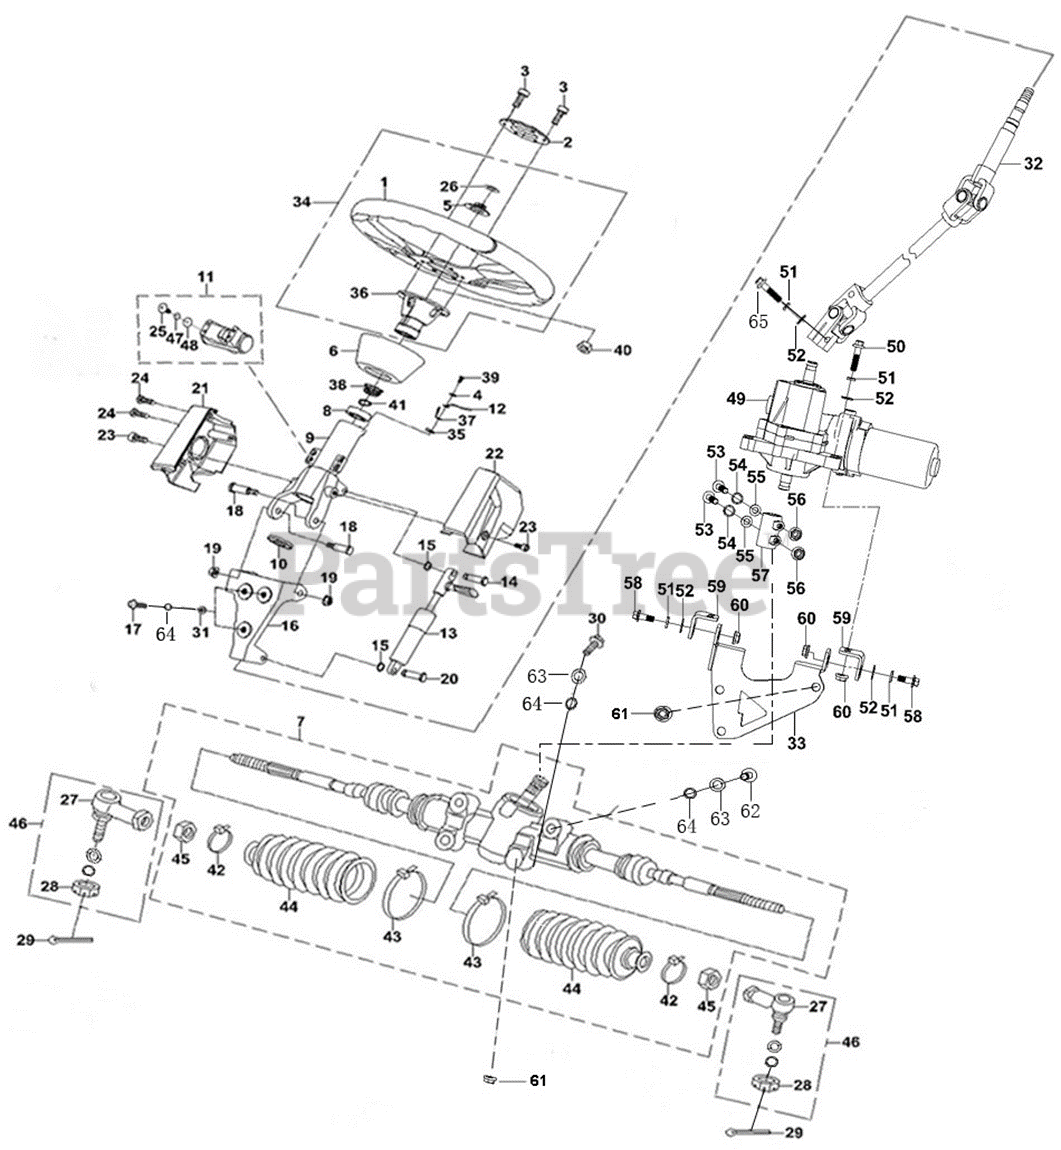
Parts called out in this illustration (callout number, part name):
1	STEERING WHEEL ASSEMBLY
2	STEERING WHEEL CAP
3	SOCKET HEXAGON SCREW M6X16
4	WASHER - HORN
5	SWITCH - HORN
6	STEERING POST COVER KIT
7	STEERING ASSEMBLY
8	BEARING 6003-2RZ
9	STEERING COLUMN COVER
10	BEARING 6805
11	KEY SWITCH (MY19)
12	HORN GROUND WIRE
13	GAS SPRING WHEEL ASSEMBLY
14	SHOULDER COTTER PIN 8X34
16	MOUNTING BRACKET
17	HEX FLANGE BOLT M10X1.25X20
18	SHOULDER BOLT M6X10X2.5X30.5
19	LOCK NUT M6
20	SHOULDER COTTER PIN 8X45
21	STEERING COLUMN COVER III
22	STEERING COLUMN COVER II
23	HEX HEAD FLANGE BOLT M6X12
24	SCREW - SELF TAPPING ST3.9X13
25	PAN HEAD SCREW M5X16
26	INSTRUMENT PANEL SEAL
27	Ball joint assembly
28	HEX THIN SLOTTED NUT M12X1.25
29	COTTER PIN 2X30
30	HEX HEAD FLANGE BOLT M10X1.25-40
31	WASHER 10X32X5
32	SHAFT - WHEEL ASSEMBLY
32	EPS STEERING SHAFT
33	EPS MOUNTING BRACKET
34	STEERING WHEEL ASSEMBLY
35	HORN INSULATION WASHER
36	CONNECTING WHEEL FLANGE
37	HORN REED SWITCH
38	SPRING HORN SWITCH
39	CROSS HEAD SCREW M4X10
40	LOCK NUT M12X1.25
42	SPRING CLAMP
43	DIRT-PROOF BOOT CLAMP
44	DIRT-PROOF BOOT
45	NUT M14X1.5
46	BALL JOINT ASSEMBLY
47	SPRING WASHER
49	ELECTRICAL POWER STEERING COMP
49	EPS MOTOR (180W-450L)
49	EPS SENSOR
49	EPS COMPONENT
49	ESP SENSOR COVER
50	HEXAGON FLANGE BOLTS M8X35
52	SPRING WASHER-8
53	HEX FLANGE BOLT M8x40
55	SPRING WASHER
56	NUT HEXAGON FLANGE HEAD M8
57	EPS ADAPTER SLEEVE
58	HEXAGON FLANGE BOLT M8X20
59	EPS MOUNTING BRACKET I
60	NUT HEXAGON FLANGE HEAD M8
61	LOCK NUT M10X1.25
62	HEX FLANGE BOLT M10X1.25X45
64	SPRING WASHER
65	HEXAGON FLANGE BOLT M8X30
